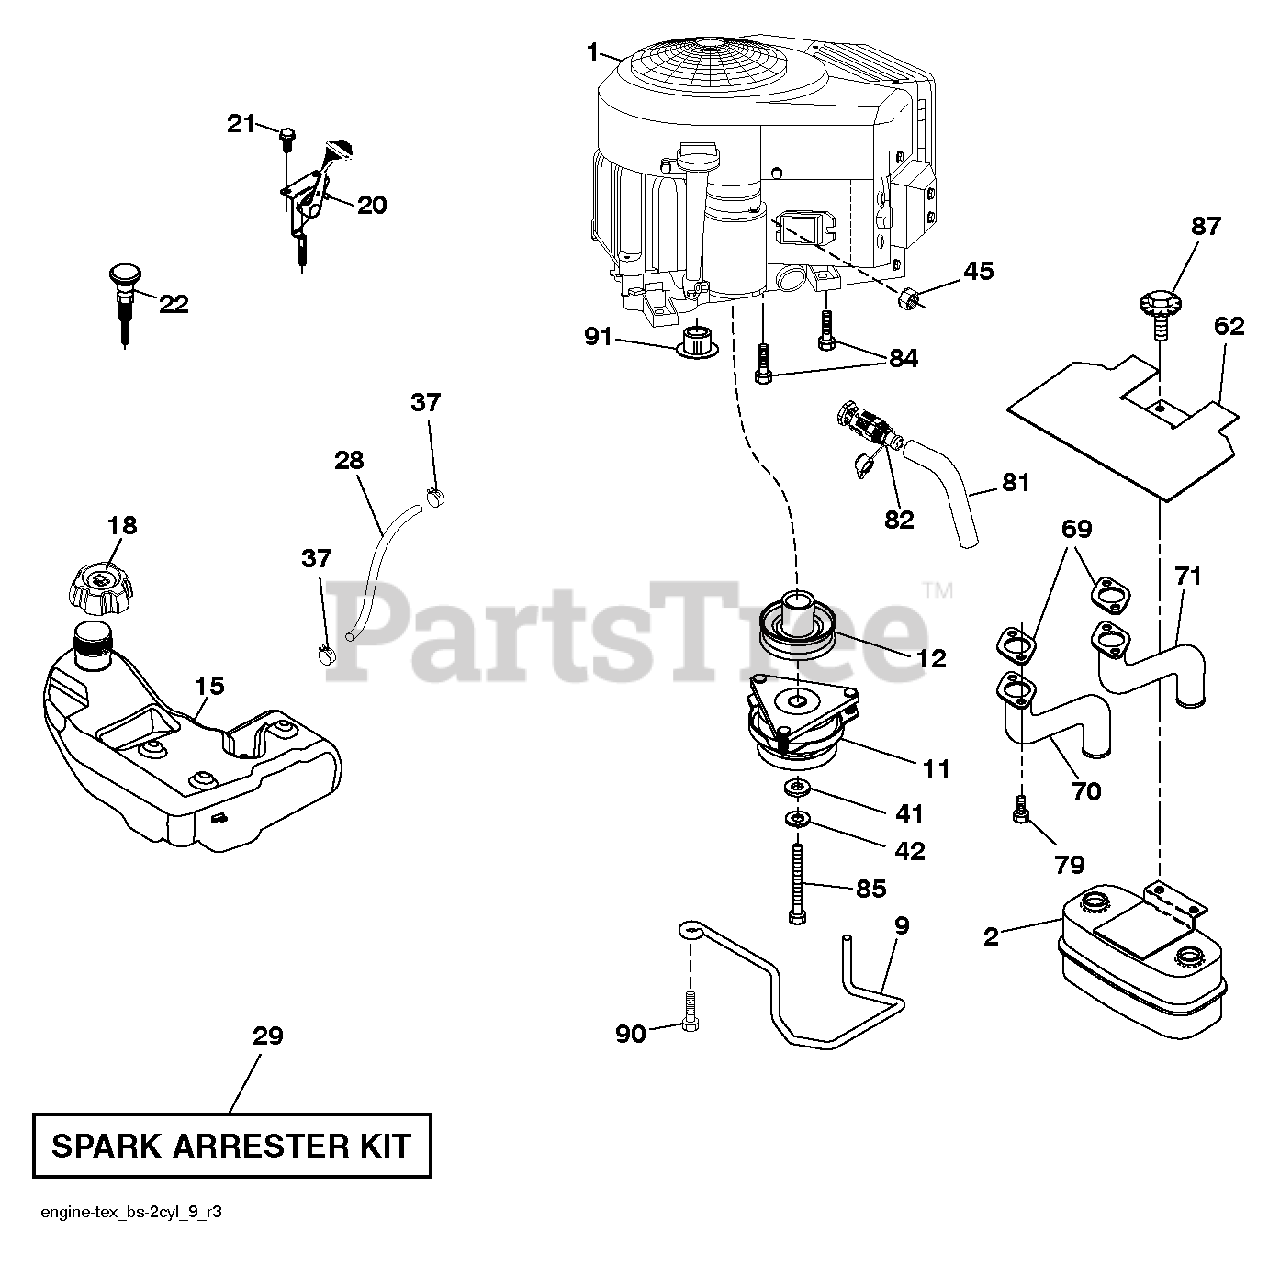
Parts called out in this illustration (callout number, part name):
2	MUFFLER.TWIN.CYL.LOW.TONE
9	KEEPER.BELT.ENGINE.4.2
11	CLUTCH ELECTRIC
12	PULLEY ENGINE
15	TANK.FUEL.4GAL
18	CAP.ASM.FUEL.TANK.3"BLACK
20	CONTROL.TH/CK.COBRA.B&S.TWN.
21	SCREW.#10 X 0.750.BOS (2 2)
22	CONTROL CHOKE
28	LINE.FUEL.64"REAR.EMIS
29	KIT.SPARK ARRESTOR(392390 B&S)
37	HOSE CLAMP
42	LOCKWASHER
45	NUT
62	SHIELD.HEAT.MUFFLER
69	GASKET.MUFFLER
70	RP.EXHAUST.TUBE.LH.BS/TWIN
71	RP.EXHAUST.TUBE.RH.BS/TWIN
79	SCREW.SOCKET.HEAD.5/16-18
81	TUBE, DRAIN OIL ASM.
82	VALUE.OIL.DRAIN
84	SCREW.3/8-16
85	BOLT HEX 7/16-20 X 3.75 GR. 5
87	BOLT.5/16-18UNCX1.W/SEMS.BLK
90	SCREW 3/8-16X1
91	BUSHING.1.375OD
